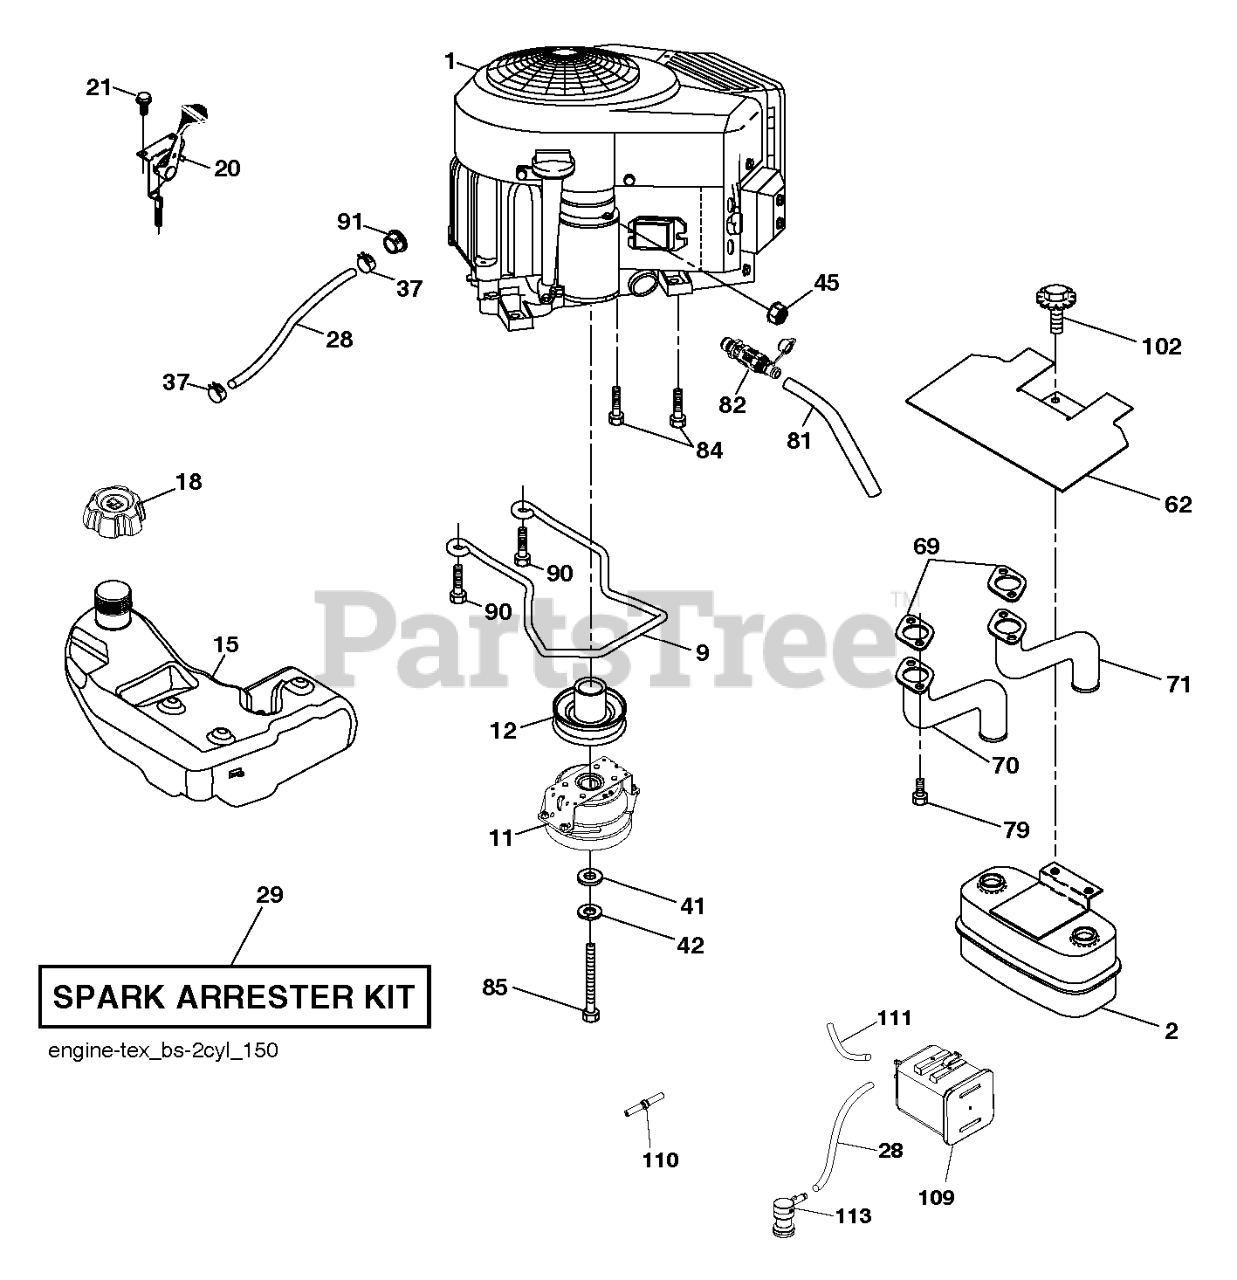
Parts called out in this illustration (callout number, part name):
2	MUFFLER.ASM.TWN.EXTNDED.DFLCTR
9	KEEPER.BELT.ENG.4.25"2.BLT.431
11	CLUTCH.OGURA.4.4PD.GT1.5-EH13V
12	PULLEY.ENGINE.TUFFTORQ
15	TANK.ASM.FUEL.3GA.CARB
18	CAP ASSY FUEL 3" GRAY
20	CONTROL.TH/CK.COBRA.B&S.TWN.BK
21	SCREW.#10 X 0.750.BOS
28	LINE.FUEL.64"REAR.EMIS
29	KIT.SPARK ARRESTOR 794945 B&S
37	HOSE CLAMP
42	LOCKWASHER
45	NUT
62	SHIELD.HEAT.MUFFLER
69	GASKET.MUFFLER
70	EXHAUST.TUBE.LH.BS/TWIN
71	EXHAUST.TUBE.RH.B&S.TWIN.INTEK
79	SCREW.SOCKET.HEAD.5/16-18
81	TUBE, DRAIN OIL ASM.
82	VALUE.OIL.DRAIN
84	SCREW.3/8-16
85	CLUTCH BOLT7/16-20X3.5 GR524HR
90	SCREW 3/8-16X1
91	BUSHING.1.375OD
102	SCREW
109	CANNISTER, CARBON
110	VALVE.ASM.ANTI-SLOSH
111	RP PURGE LINE
113	VALVE.SLANT.CARTRDG.90 DEG.TEX
